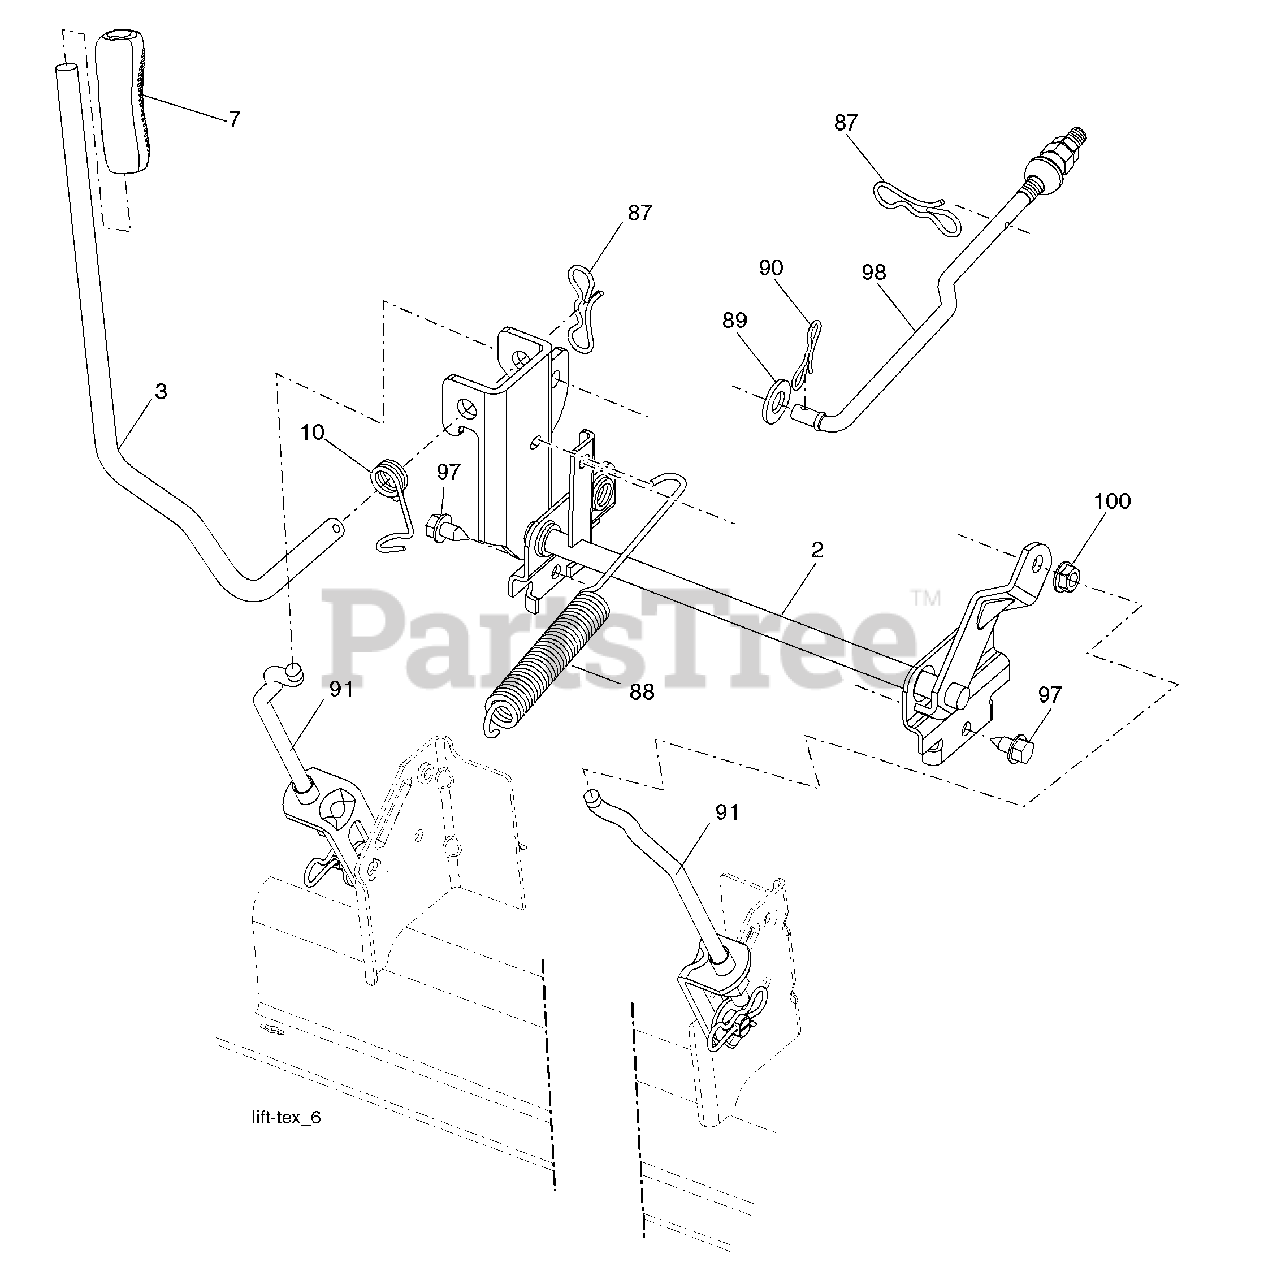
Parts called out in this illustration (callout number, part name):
2	Shaft Asm., Lift
3	Lever Asm., Lift RH
7	Grip, Lever
10	Spring Torsion
87	Pin Cotter 7/16 Bow Tie Lock
88	Spring Lift Assist
89	Washer Clear Zinc
90	Pin Cotter 5/16 Bow Tie Lock
91	Link Lift Susp Mower Rear
97	Screw 3/8-16 x 3/4
98	Link Lift Susp. Front Mower
100	Nut Centerlock 3/8-16
